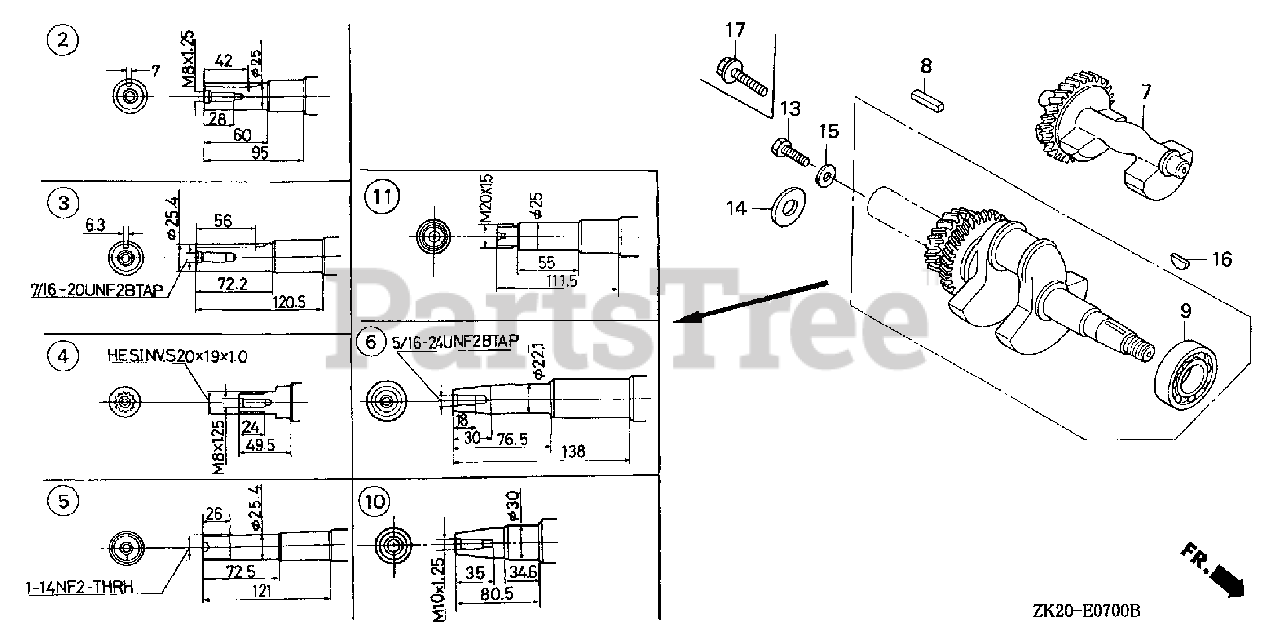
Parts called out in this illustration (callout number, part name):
6	CRANKSHAFT (V-TYPE)
7	WEIGHT, BALANCER
9	BEARING, RADIAL BALL (6206)
